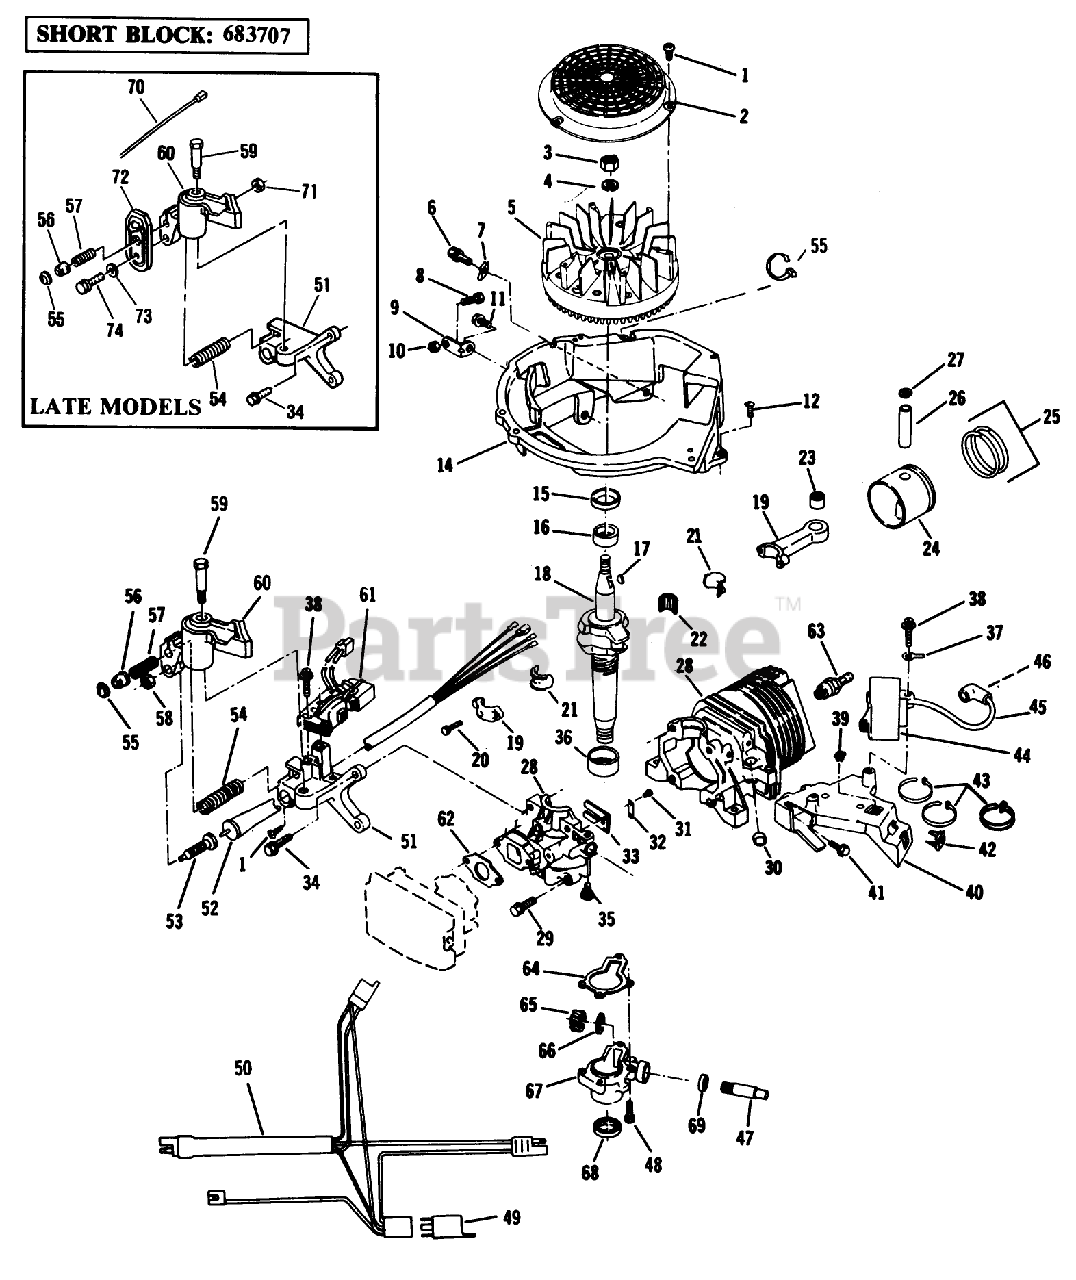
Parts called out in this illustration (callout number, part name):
1	SCREW F
2	SCREEN F'WHEEL S
3	NUT
5	FLYWHEEL ASSY F
6	SCREW-SEMS
8	BOLT F
10	NUT-LOCK F
12	SCREW F
14	BASE SHROUD F
16	BEARING V
17	KEY
20	SCREW-HSH
21	LINER ASM
23	BEARING AY F
27	RING-RETAINING
29	SCREW S
30	PLUG-CORE VF
32	PLATE-BACKUP, REED
36	BEARING S
37	TERMINAL S
39	NUT-CLIP
42	NUT-CLIP
45	HT LEAD&COVER XEV
51	BRACKET F
51	BRACKET-BRAKE F
53	PLUNGER S
54	SPRING-BRAKE
55	RETAINER S
56	ACTUATOR-LEVER, BRAKE
57	SPRING
62	GASKET CARB S
64	GASKET S
65	GEAR, DR SHAFT S
66	THRUST WASHER
68	SEAL-OIL
69	SEAL S
70	WIRE LEAD AY F
71	NUT C/LOCK E
73	WASHER
